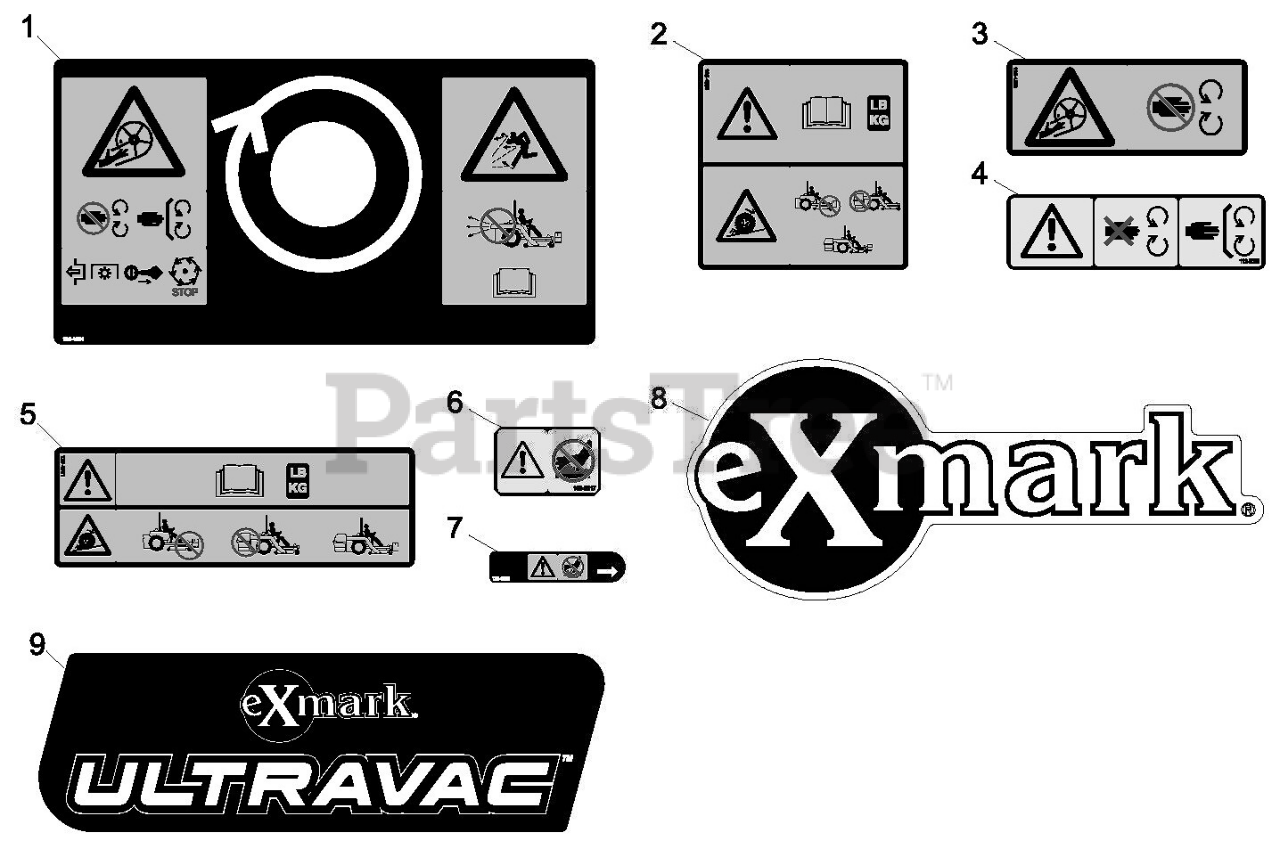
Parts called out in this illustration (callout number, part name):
1	Decal-Warning Blower
2	DECAL-WARNING, TRACTION
3	Decal-Blower Impeller Hazard
4	DECAL-COVER, MISSING
5	DECAL-WARNING WEIGHT
6	DECAL-WARNING
7	DECAL-WARNING
8	DECAL-EXMARK LOGO
9	Decal, Ultra Vac
